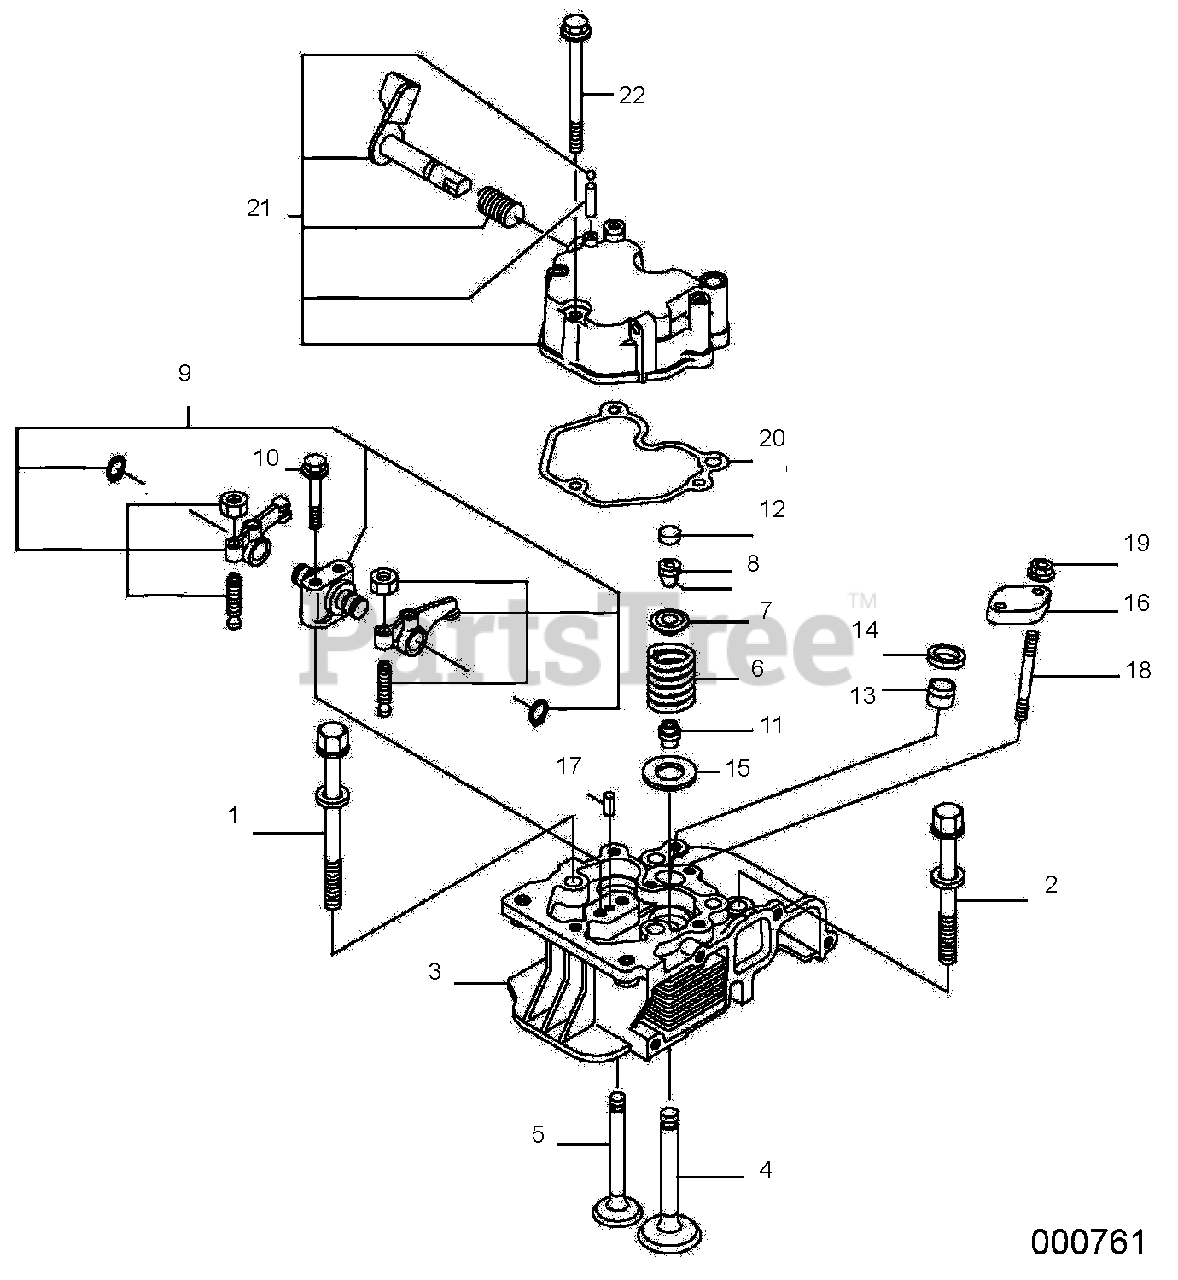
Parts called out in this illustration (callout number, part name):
1	CYLINDER HEAD BOLT (A)
2	CYLINDER HEAD BOLT (B)
3	CYLINDER HEAD ASSEMBLY
4	INTAKE VALVE
5	EXHAUST VALVE
6	VALVE SPRING
7	SPRING RETAINER
8	COTTER ASSEMBLY
9	ROCKER ARM SUPPORT ASSEMBLY
10	SUPPORT BOLT
11	VALVE STEM SEAL
12	VALVE CAP
13	NOZZLE PROTECTOR
14	NOZZLE SEAT
16	NOZZLE RETAINER
17	SPRING PIN (4.0X8)
18	STUD (M6X55)
20	VALVE COVER GASKET
21	VALVE COVER ASSEMBLY
22	PLATED BOLT (M6X65)
